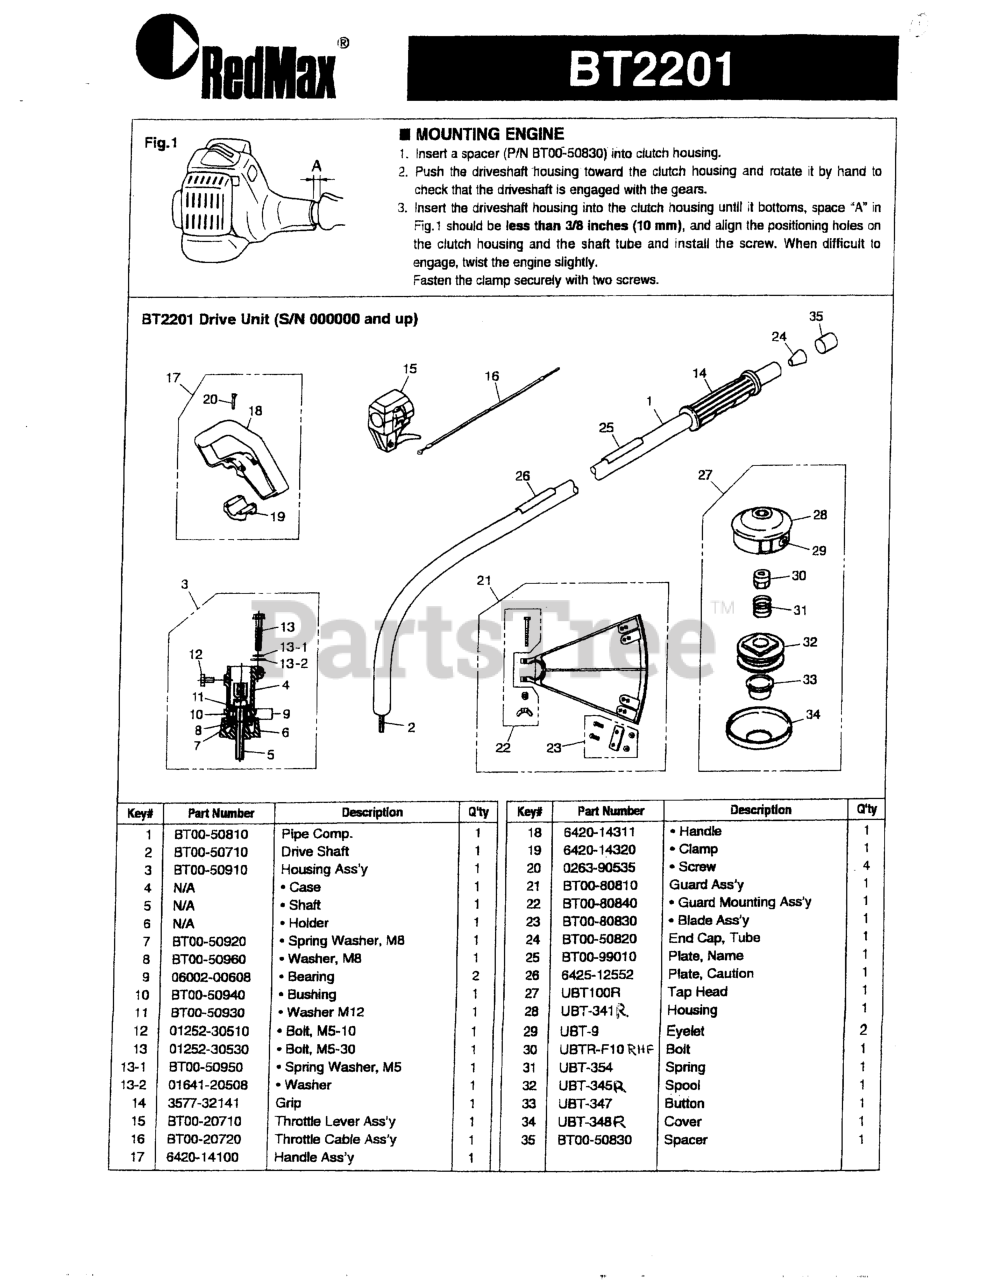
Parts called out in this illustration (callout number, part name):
1	PIPE COMPLETE
3	HOUSING ASSEMBLY
4	CASE (N/A)
5	SHAFT (N/A)
6	HOLDER (N/A)
7	WASHER, M8
8	WASHER, M8
9	BEARING (RPLS. T4001-31340)
11	WASHER, M12
12	BOLT, M5 X 10
13	BOLT, M5 X 30
13-1	WASHER, M5
13-2	WASHER, M5 X .8
14	GRIP (RPLS 3577-32140 & 3220-
15	THROTTLE LEVER ASSEMBLY
16	THROTTLE CABLE ASSEMBLY
17	HANDLE ASSEMBLY
18	HANDLE
20	SCREW, M5 x 35
21	GUARD ASSEMBLY
22	GUARD MOUNTING ASSEMBLY
23	BLADE ASSEMBLY
24	END CAP, TUBE
25	LABEL (BT2201)
26	PLATE, CAUTION
27	HEAD (BT2201) (ACC.)
28	HOUSING
29	EYELET
30	UBTR-F10-RHF
31	SPRING
33	BUTTON
35	SPACER (USE 6367-13990)
